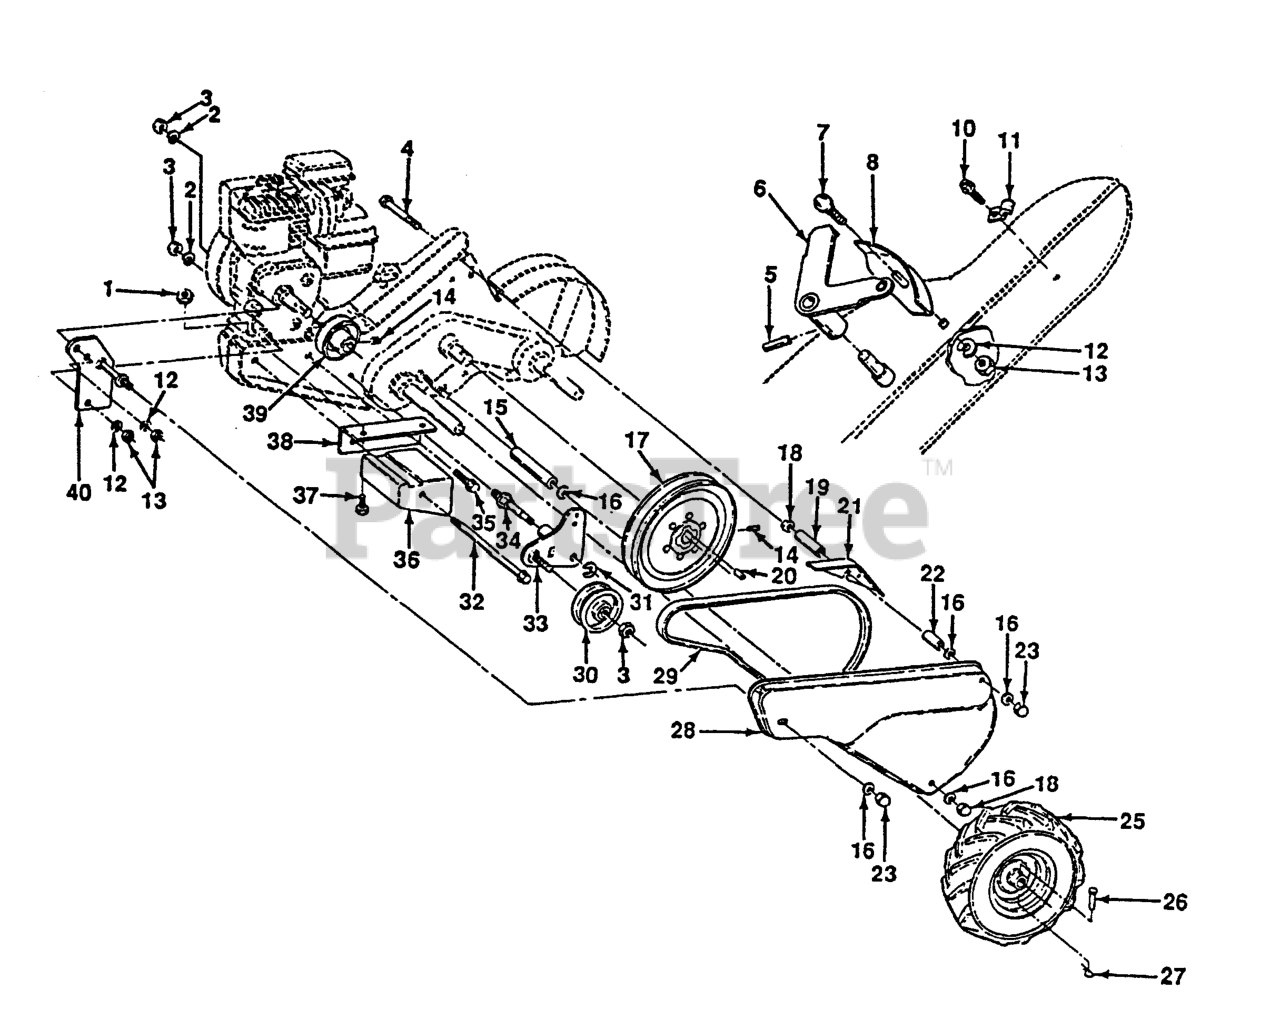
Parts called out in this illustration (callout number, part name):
1	NUT
2	WASHER, LOCK 3/8
3	NUT.HEX.3/8-16UNC
4	Bolt, Hex 5/16-18 x 4-3/4
5	DRIVE PIN
6	LEVER ASM CRT
8	PANEL.INDICATOR.SHIFT.BLACK
10	TAPPING SCREW
11	CONDUIT.CLIP.PLATED
12	LOCKWASHER
13	NUT
16	WASHER
17	SHEAVE 10" CRT
18	NUT
19	SPACER CRT
22	SPACER CRT
25	TIRE.13X5-6.CHEVRON.TILLER
25	RIM ASM.6"WHITE.TILLER
25	VALVE STEM LT
26	RIVET,DRILLED
27	RETAINER M
29	V-BELT CRT
30	PULLEY-IDLER TI
32	BOLT.FIN.HEX.3/8-16UNC
33	BRACKET ASSY TI
34	SHIFT ARM CRT
35	BOLT
36	COUNTERWEIGHT.LH.CRT
37	BOLT
38	BRACKET LH CRT
39	SHEAVE ENGINE CRT
40	BRACKET ASSY CRT
40	DECAL TI NLA
40	DECAL, BELT GRD
